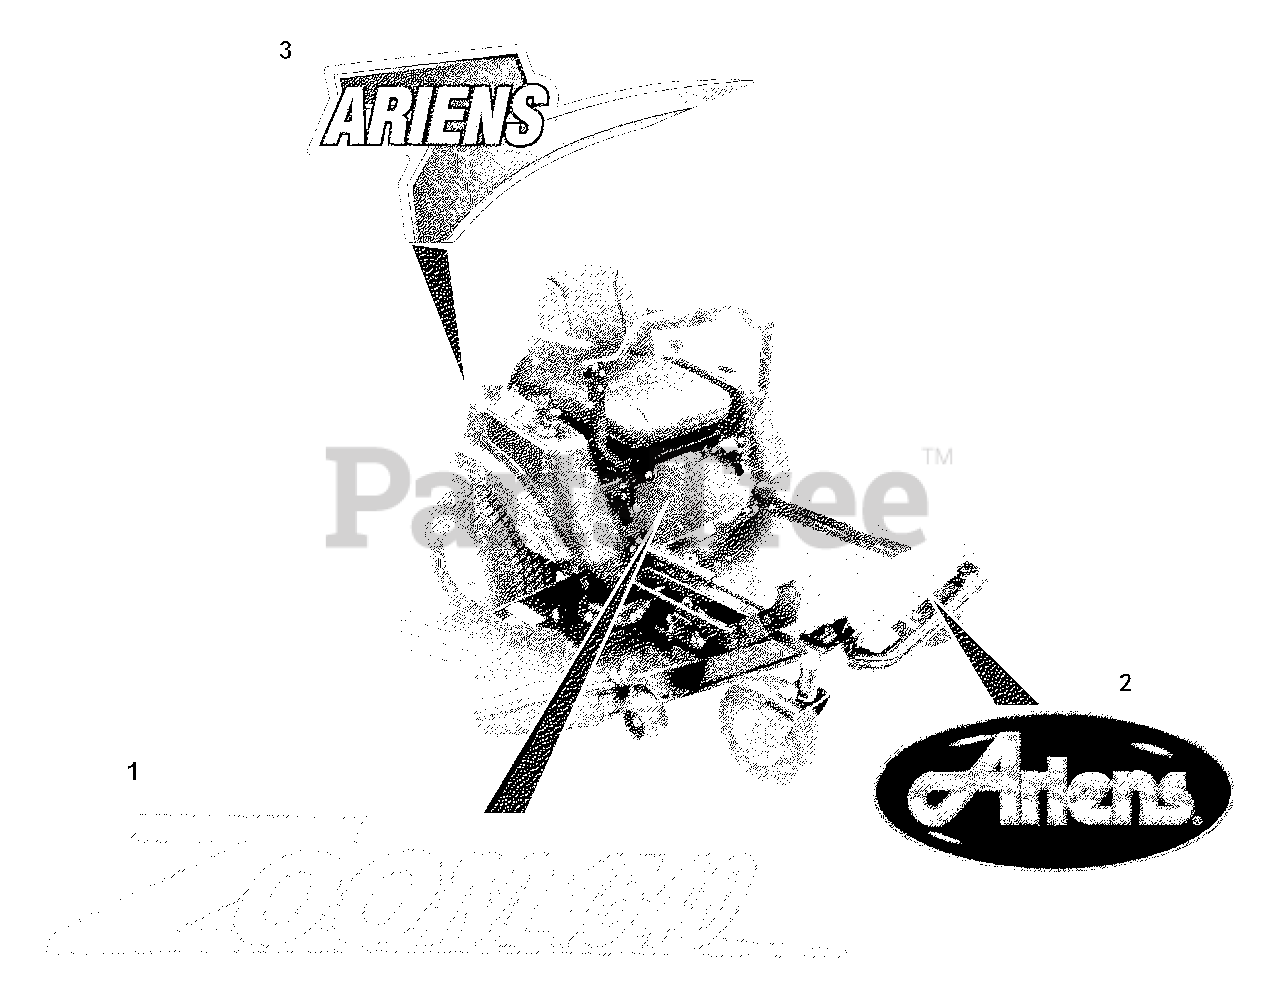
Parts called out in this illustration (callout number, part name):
1	DECAL,ZOOM 1944
2	DECAL-ARIENS JEWEL
3	DECAL, ZOOM HOOD
